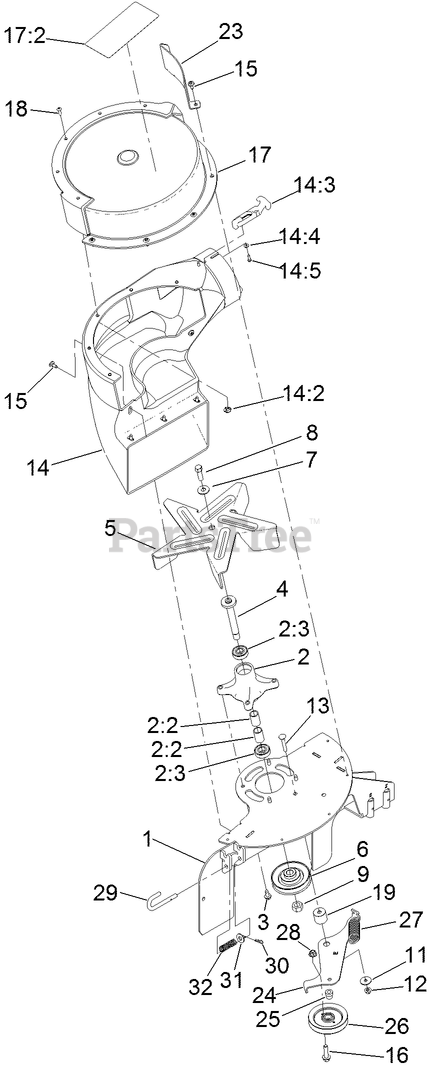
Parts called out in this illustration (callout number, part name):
1	SUPPORT-BLOWER
2	SPINDLE ASM
2:2	SPACER
2:3	BEARING-BALL
3	SCREW-HWHTF
4	SHAFT - SPINDLE
5	FAN-BLOWER
6	SHEAVE-OFFSET
7	WASHER-BELLEVILLE
8	SCREW-HH
9	NUT-HEX
11	WASHER-PIVOT
12	NUT-HF, NI
13	SCREW-CARR
14	BLOWER CHUTE ASM
14:2	INSERT-T-NUT
14:3	LATCH-RUBBER
14:4	WASHER-FLAT
14:5	SCREW-PPH
15	SCREW-SHOULDER
16	SCREW-HHF
17	BLOWER COVER ASM
17:2	DECAL-DANGER
18	SCREW-PRH
19	SPACER-STEPPED
23	GUARD-BLOWER
24	ARM-IDLER
25	SPACER-HUB
26	Flat-Idler
27	SPRING-IDLER
28	NUT-HF, NI
29	PIN-LATCH
31	WASHER-FLAT
32	SPRING-COMPRESSION
